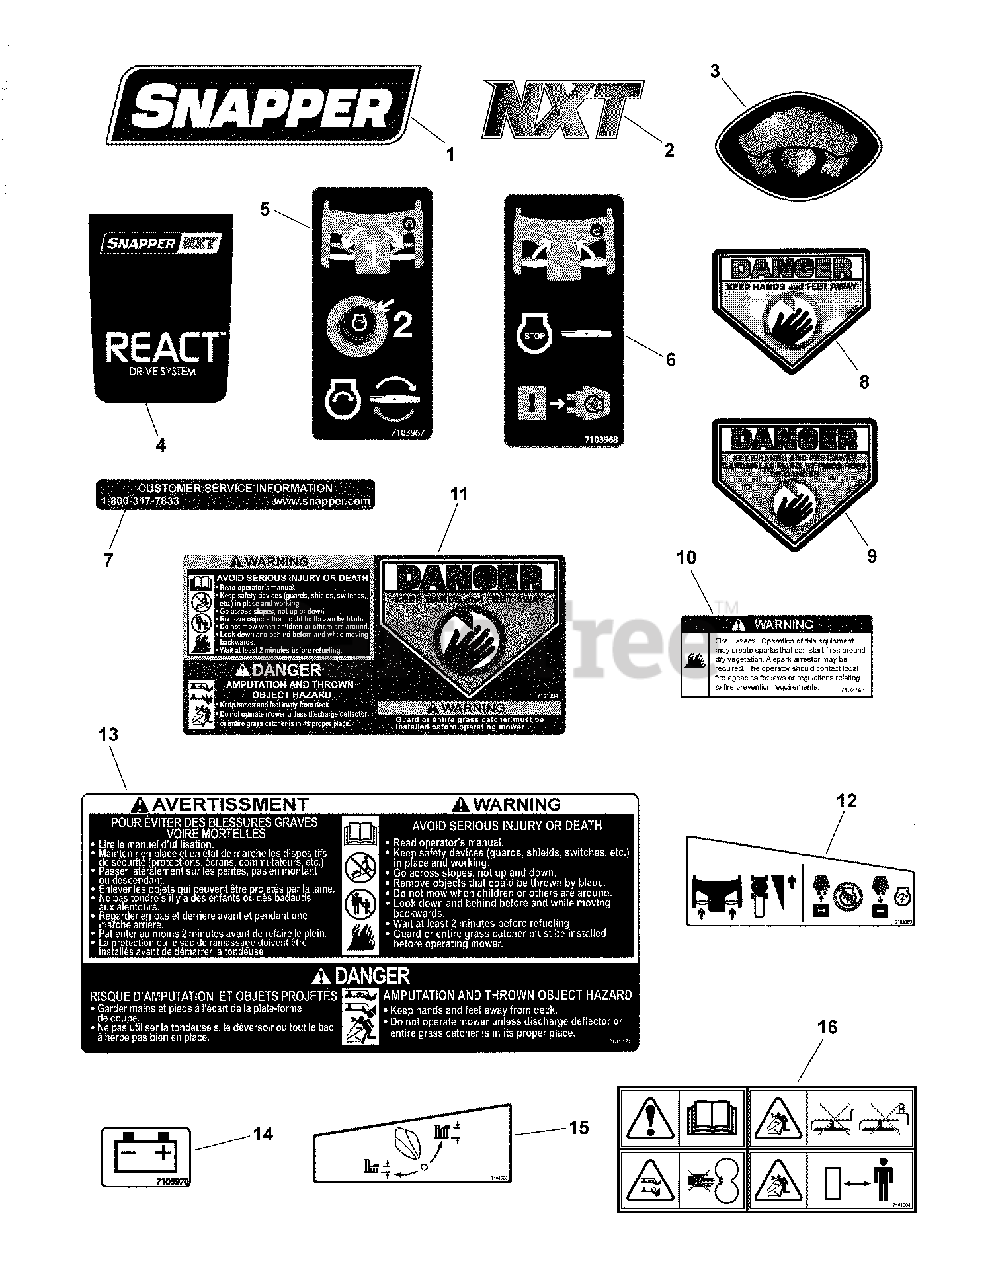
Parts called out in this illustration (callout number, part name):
1	DECAL, Front Shroud, Snapper Logo
2	DECAL, Front Shroud, NXT Logo
3	DECAL, Handle, Domed Turtle
4	DECAL, Handle, React Drive
5	DECAL, Start NXT
6	DECAL, Stop NXT
7	DECAL, Customer Service, MY08, Snapper
8	DECAL, Danger, Cut Finger
9	DECAL, CPSC, French/English
10	DECAL, Arrestor, Spark
11	DECAL, Warning, Rear Discharge Door
12	DECAL, Key Switch
13	DECAL, French/English, WB Safety
14	DECAL, Battery
15	DECAL, Electric Height-of-Cut
16	DECAL, Warning, Euro, Multi-Panel
